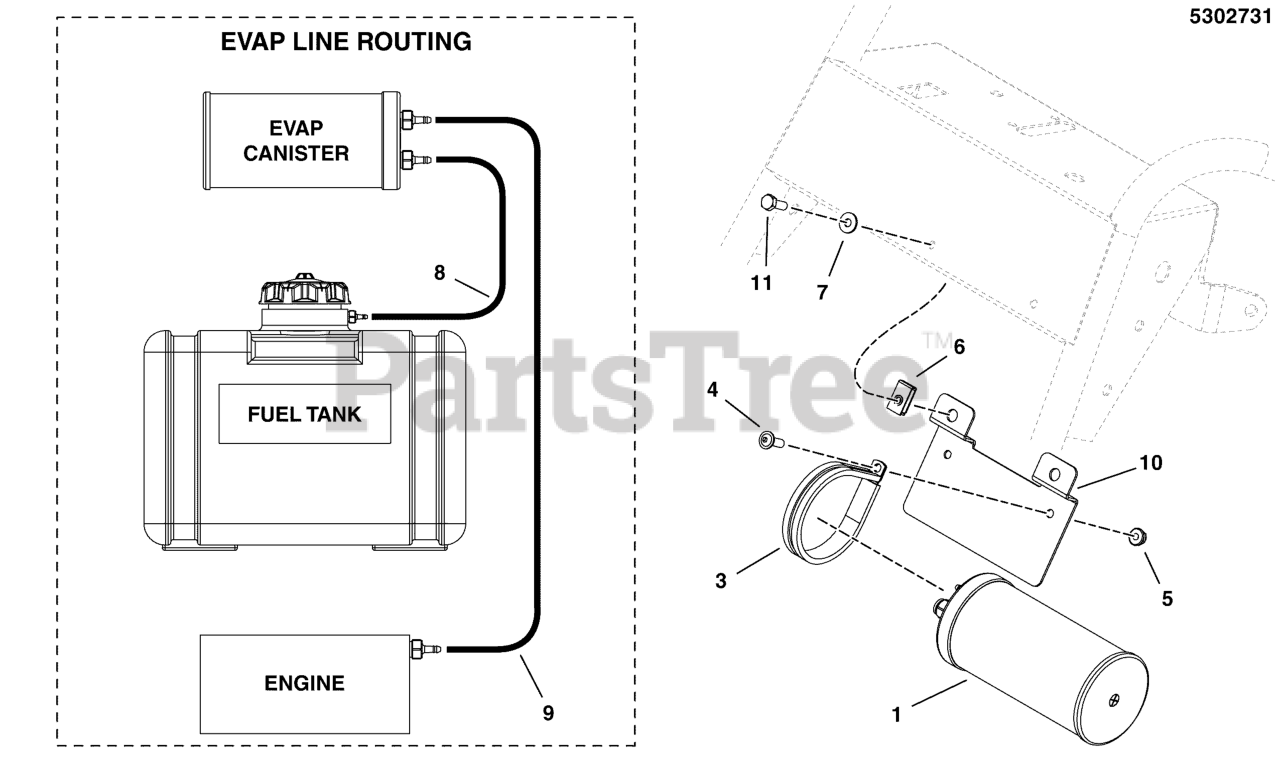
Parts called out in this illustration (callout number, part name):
1	CNSTR, CARB, 6 GAL
2	DECAL, EPA CERT, WALKS
3	CLAMP, 3" ID, CUSHIONED, STAINLESS
5	NUT, 1/4-20 HEX NYLOCK FLANGE
6	BODY CLIP, 1/4-20 X 1/2 DEEP
7	WASHER, 1/4 SAE
8	HOSE, VAPOR, 5MM ID, 11.50 LG
9	HOSE, VAPOR, 5MM ID, 60.00 LG
10	PLATE, CARB CANISTER MOUNT, HC/PACER
11	BOLT, 1/4-20 X 3/4
